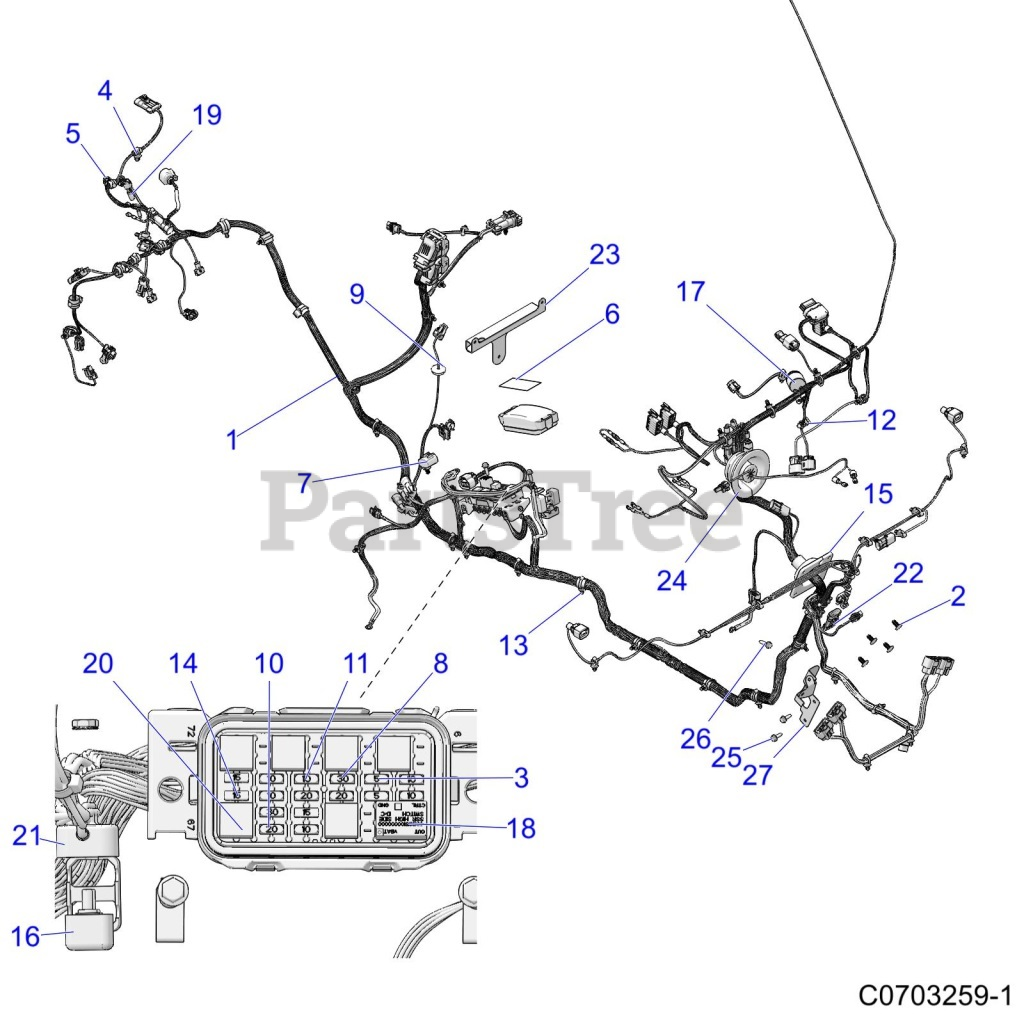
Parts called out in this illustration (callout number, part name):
1	HARNESS-MAIN,GAS,STD
2	CLIP-PLASTIC, DART, NYLON
3	FUSE-5A,MINI BLADE
4	CLIP-FIR TREE, 9, 7-10MM HOLE
5	CLIP-EDGE, 1-3MM THICKNESS
6	DECAL-RELAY/FUSE BLOCK,GAS
7	COVER-DIAGNOSTIC,W/CLIP
8	FUSE,MAIN,30 AMP,(10)
9	GROMMET - USB, 3 MM, 22 MM DIA
10	FUSE, 20 AMP, PARK
11	FUSE,IGN.10 AMP,(10)
12	CLIP-EDGE, 1-3MM THICKNESS
13	CLIP-ROUTING
14	FUSE, MINI BLADE, 15 AMP
15	GROMMET - 65MM, W/FLANGE, BLK
16	BREAKER-CIRCUIT,20 AMP,SEALED
17	ALARM-BRAKE, WARNING
18	RELAY - SSR 10A
19	CAP-EVAP CONNECTOR
20	RELAY-SPST,SERIES 303,SEALED
21	BOOT-CIRCUIT BREAKER, RED
22	CONNECTOR-4M,M/P150,SEALED,BK
23	BRKT-ECU,ZEUS DIESEL
24	GROMMET-HOOD LINER,SPLIT
25	SCR-M6X1.0X20,HXHD,FLG,TDFM,BL
26	SCR-TFHFL-M6X1.0X25,ZTC
27	BRKT-ROUTING,BLK
